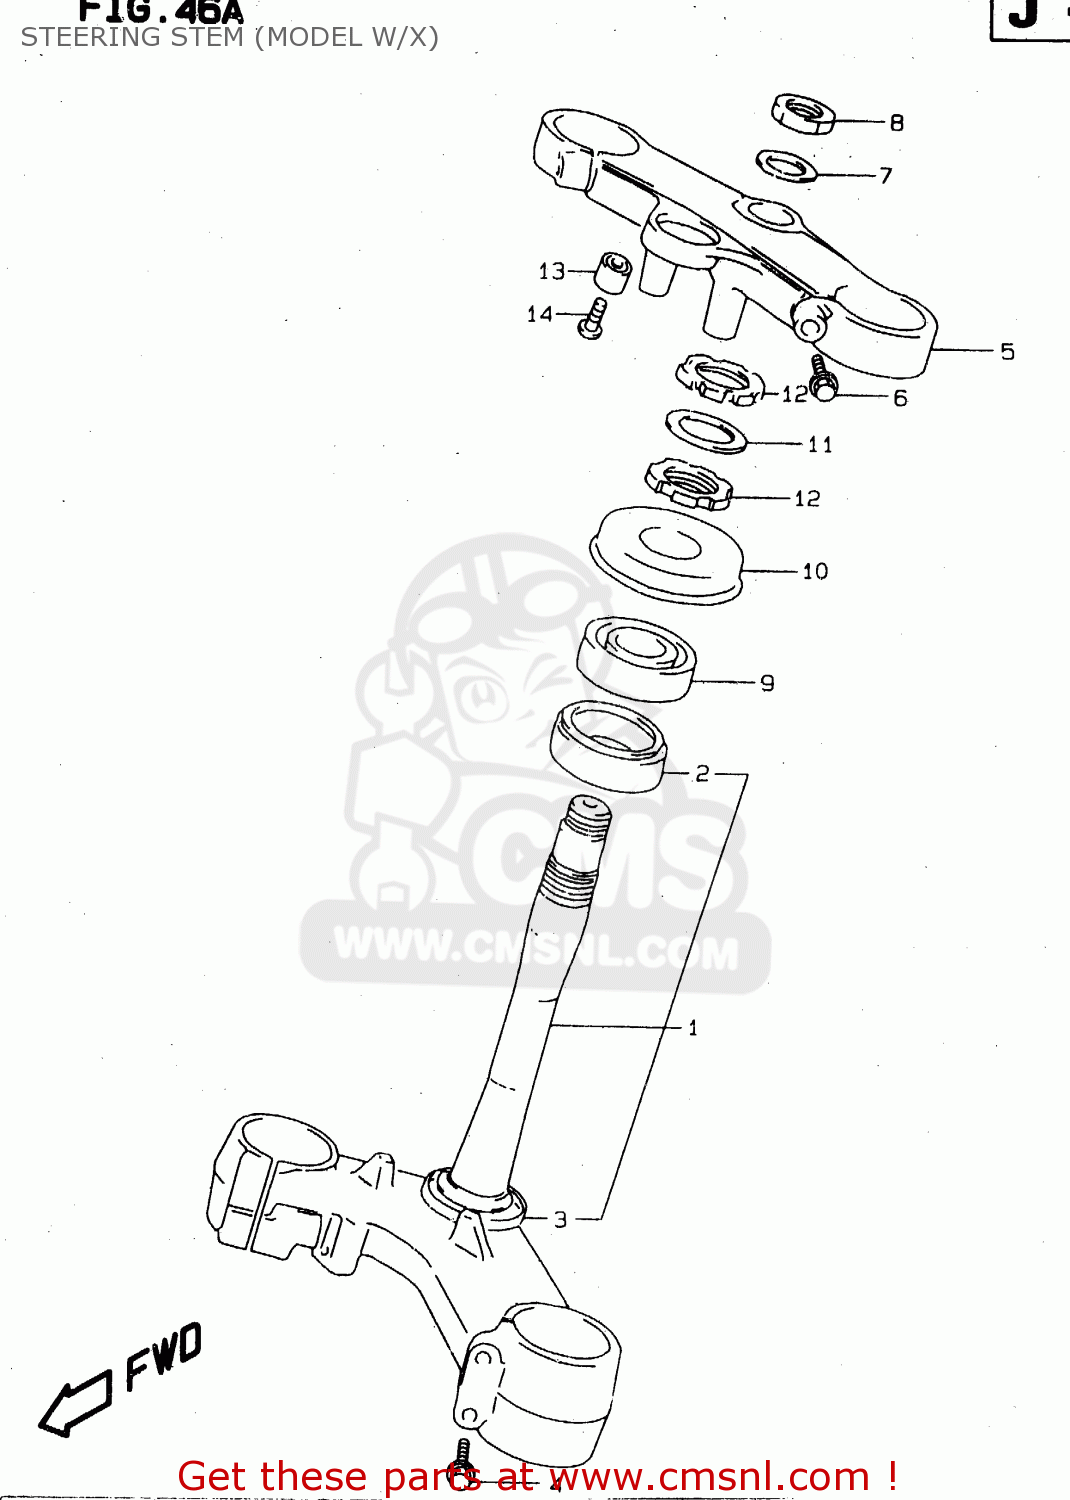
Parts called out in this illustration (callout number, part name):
1	STEM,STEERING
2	BEARING(30X55X17)
3	SEAL,STEERING LWR
4	BOLT
5	HEAD,STEERING STEM
6	BOLT
7	WASHER,STEM HEAD(24.5X34X1.6)
8	NUT
9	BEARING(30X55X17)
10	SEAL,STEERING UPR DUST
11	WASHER,STEERING STEM
12	NUT,STEERING STEM
13	BALANCER,BRACKET UPR
14	SCREW
